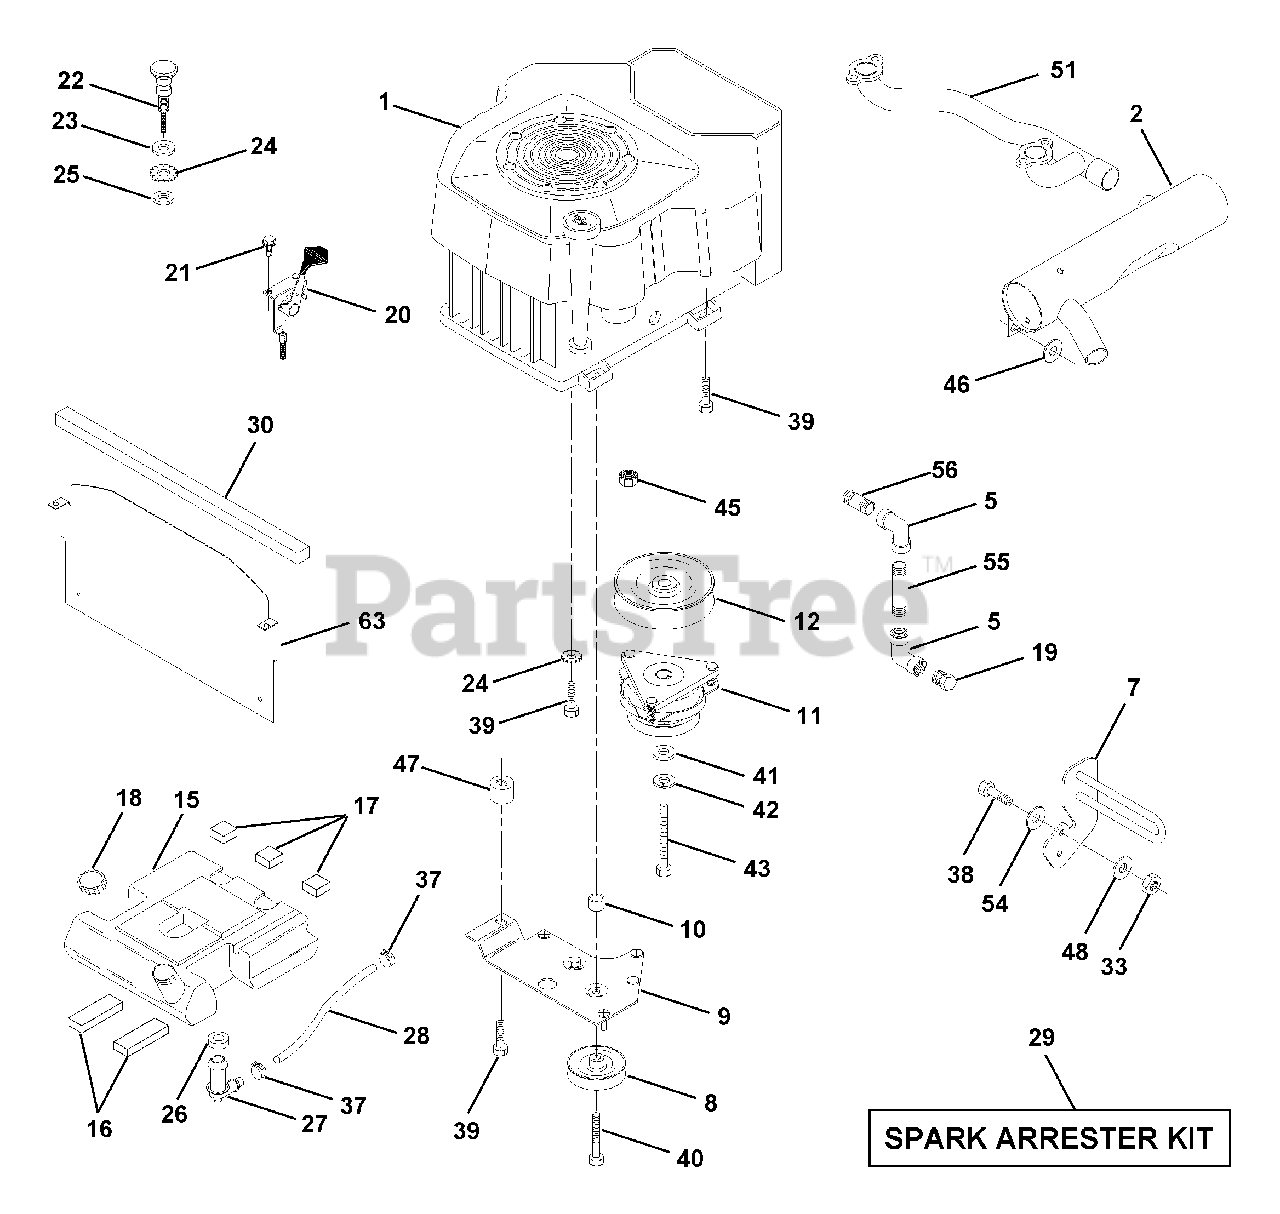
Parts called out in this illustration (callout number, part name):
2	Muffler VGT Cylinder
5	Elbow STD 90 Degree 3/8-18 NPT
7	Muffler Assembly Guard
8	Pulley V-Idler
9	Stop Keeper Asm VGT
11	Clutch Electric
12	Pulley Engine VGT Elect Clutch
15	Tank Fuel W/Sym Vented
16	Pad Spacer
17	Pad Spacer
18	Cap Asm Fuel W/Sym Vented
19	Plug Oil Drain
20	Control Throttle
21	Screw Hex Thd Cut 1/4-20 X 5/8
22	Control Choke
23	Washer 13/32 X 13/16 x 16 Ga
24	Washer Ext Tooth 3/8
25	Nut Fin Hex 3/8 - 24 UNF
26	Bushing
27	Stem Tank Fuel
28	Fuel Line
29	Spark Arrester Kit
30	Strip Foam 18"
33	Nut, Hex W/Ins. 3/8-16 UNC
37	Clamp Hose
38	Bolt, Fin Hex 3/8-16 UNC x 1-1/2
39	Screw TT 3/8-16 x 2-1/4 UNC
40	Screw TT 3/8-16 x 4 UNC
41	Washer 1-1/2 OD X 15/32 ID X .250
42	Washer Lock 7/16
43	Bolt Hex 7/16-20 X 4-1/4 Ga 5
45	Nut Flange 1/4-20 Starter Nut
46	Washer 13/32 x 1 x 16 Ga.
47	Spacer Engine
48	Washer 13/32 x 1-1/4 x 7 Ga.
51	Pipe Crossover
54	Washer Flat 13/32 x 7/8 x 14 Ga.
55	Nipple, Pipe 3/8 NPT x 4-1/2
56	Nipple, Pipe 3/8 NPT x 1.00
63	Shield, Heat VGT YP/Husq.
